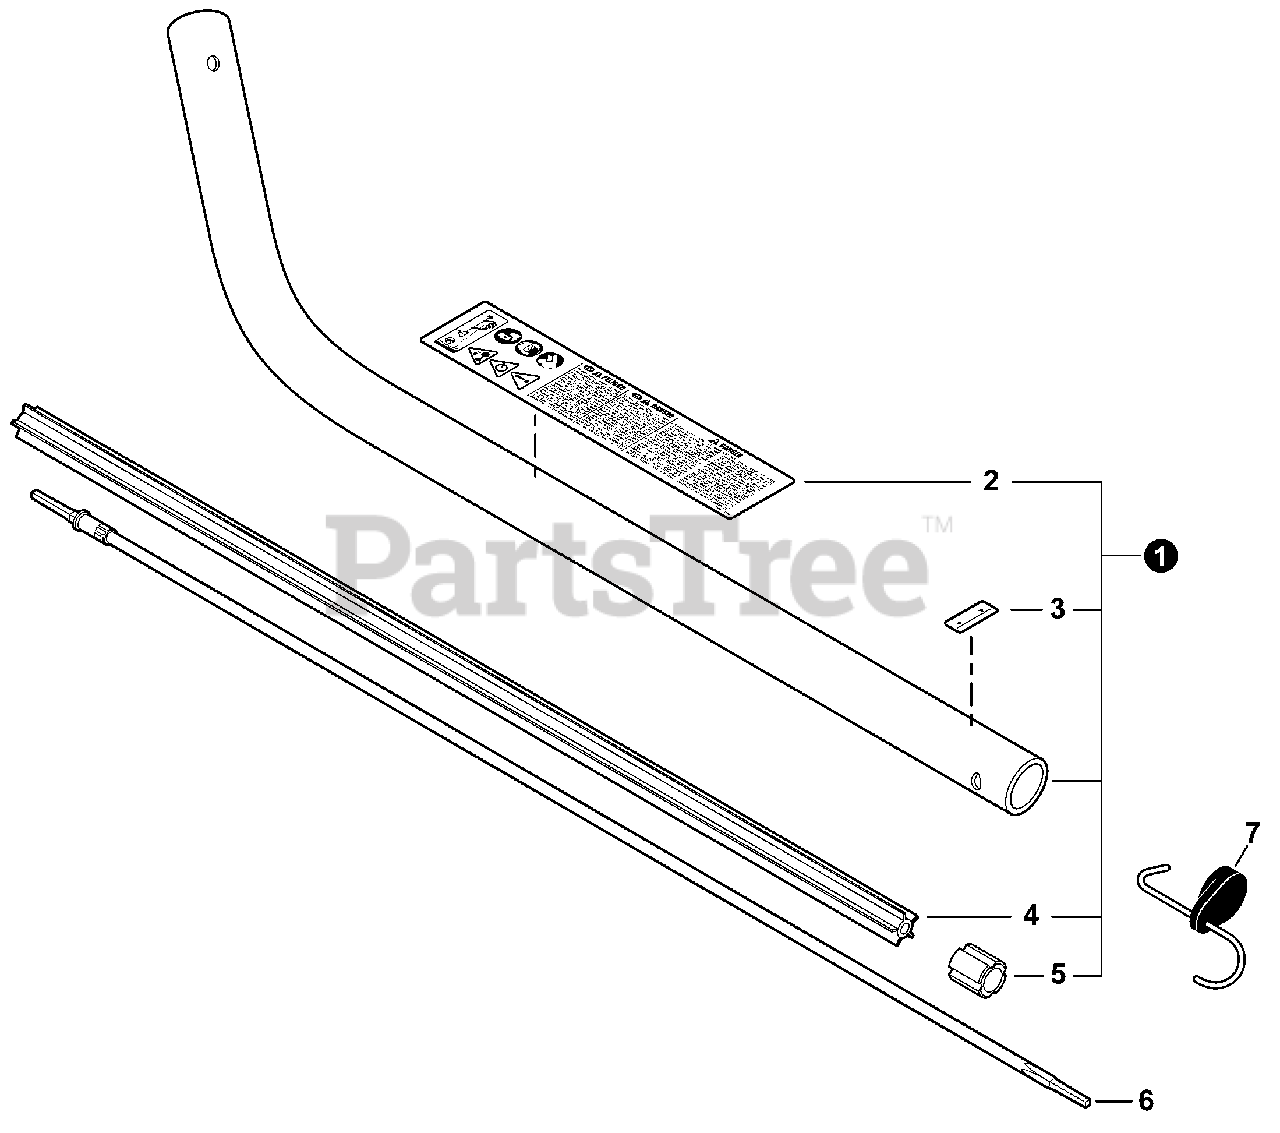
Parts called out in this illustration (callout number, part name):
1	MAIN PIPE ASSY
2	LABEL, CAUTION
3	LABEL - ALIGNMENT
4	LINER - FLEXIBLE
6	DRIVESHAFT - FLEXIBLE
7	HANGER, ATTACHMENT
